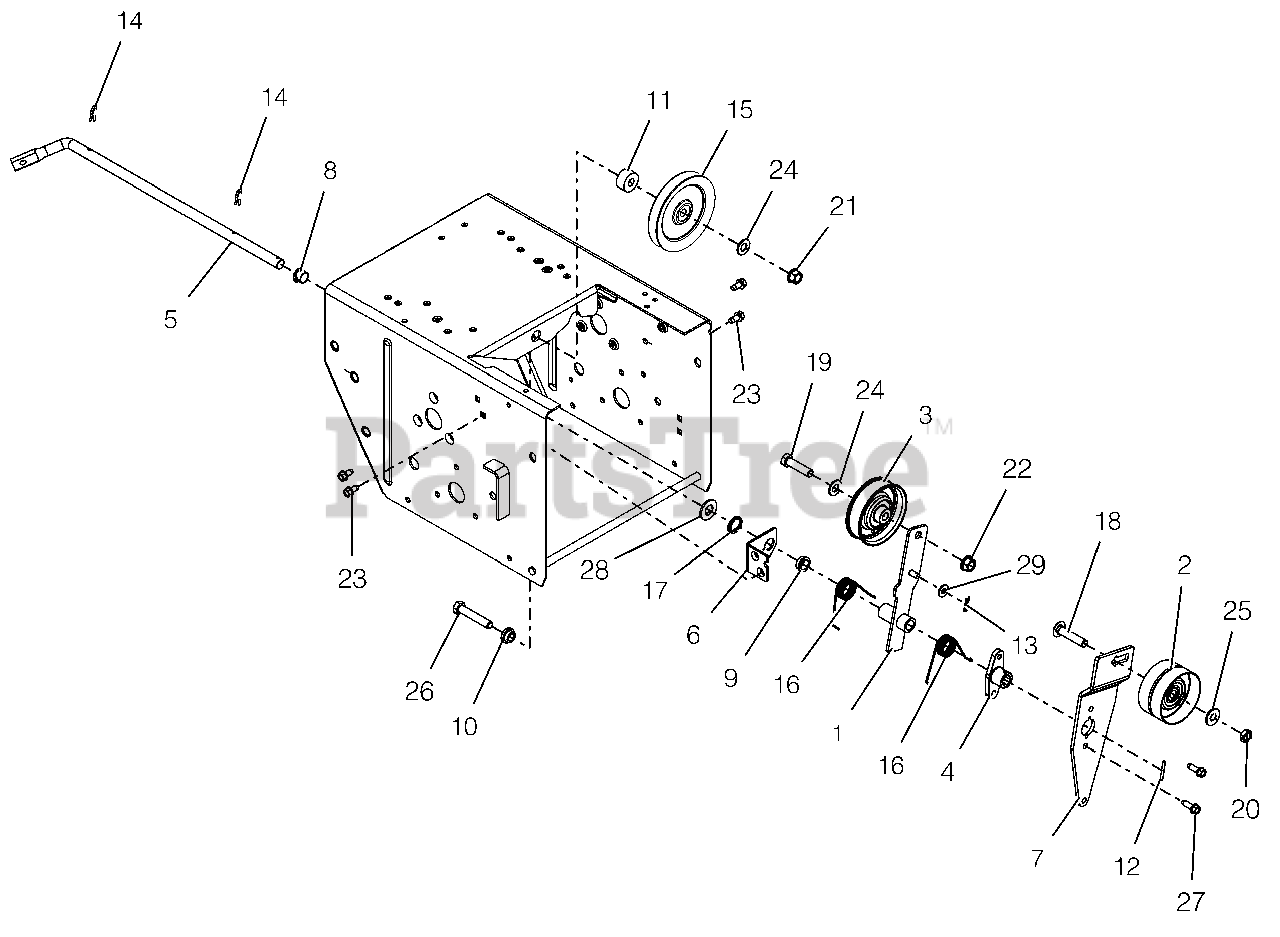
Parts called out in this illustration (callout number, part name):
1	ARM, TRACTION CLUTCH
2	IDLER, FLAT-2.75 OD X .375 ID
3	IDLER, FLAT - 3.05" X .75"
4	HUB, BRAKE ARM
5	ARM, ATTACHMENT
6	BRACKET, SUPPORT
7	ARM, IDLER-ATTACHMENT
8	BUSHING, POLYLINER-.50 SPLIT
9	BSHG,FLANGE .500X.625X.270X.75
10	BSHG, FLANGE .391X.56X.313X.75
11	BSHG,POCKET .391X.570X1.0X.450
12	PIN-ROLL .125X1.00
13	PIN-HAIR INT .06X.18X.77
14	CLIP, SPRING
15	SHV, .38"ID X 4.00"OD V-IDLER
16	SG-TORS .067X.88
17	WAVE SPRING .600X.875X.25FH
18	BLT-RHDSSQNK .38-16X1.75 G5YZ
19	@BLT-HEX .38-16X1.50 GR5 YWZC
20	@NUT-LK-CTR-JAM .375-16 YWZC
21	@NUT-LK-TOP-FLG .38-16 YWZC
22	@NUT-LK-TOP-FLG .38-16 YWZC
23	SCR-TAP .25-20X.50 HWH TR YWZ
24	@WSHR-FL-STL.406X.812X.065 YWZ
25	@WSHR-FL-STL.38X.875X.083 YWZC
26	@BLT-HEX .38-16X2.00 GR5 YWZC
27	SCR-TAP-PM .25-20X.75 TR YWZ
28	@WSHR-FL-STL.531X1.06X.095YWZC
29	@WSHR-FL-STL.281X.62X.065 YWZC
